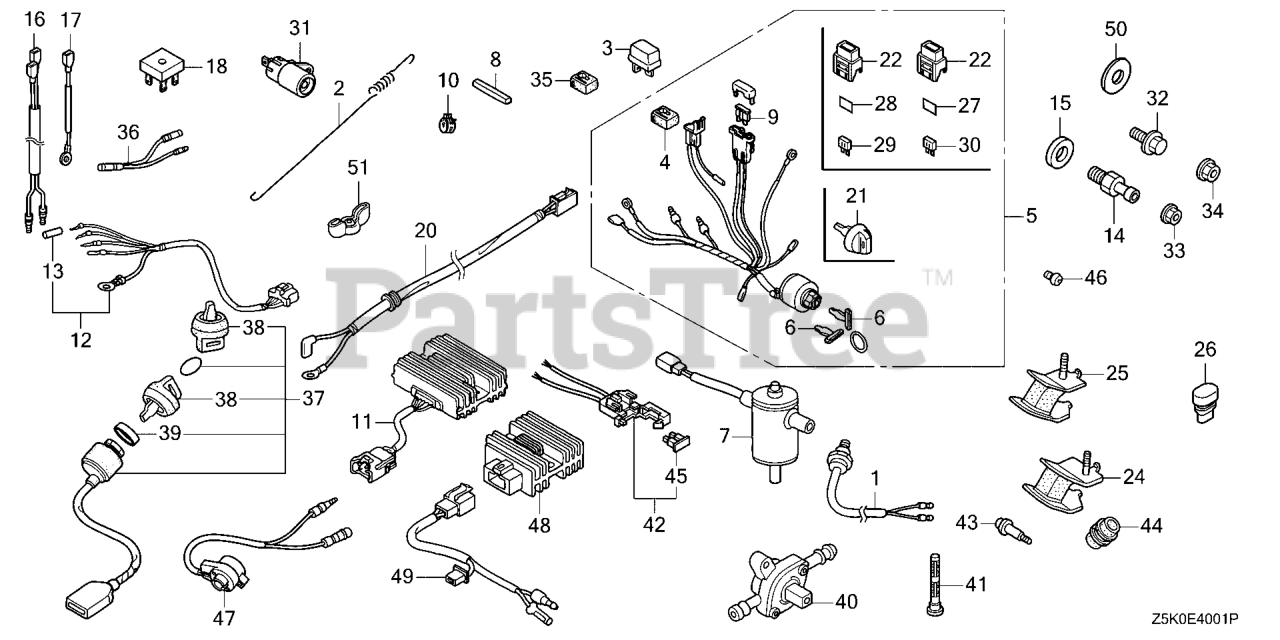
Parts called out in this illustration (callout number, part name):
5	SWITCH ASSY., COMBINATION (BUNDLE,HM,FS) (MSDS)
20	SUB-WIRE HARNESS ASSY.
21	KEY ASSY., COMBINATION SWITCH (BLACK)
22	COVER ASSY., FUSE
24	RUBBER (LOWER)
25	RUBBER (LOWER)
27	LABEL, FUSE (30A)
28	LABEL, FUSE (7.5A)
29	FUSE, MINI (7.5A)
30	FUSE, MINI (30A)
31	INDICATOR ASSY.
32	BOLT, FLANGE (6X12) (CT200)
